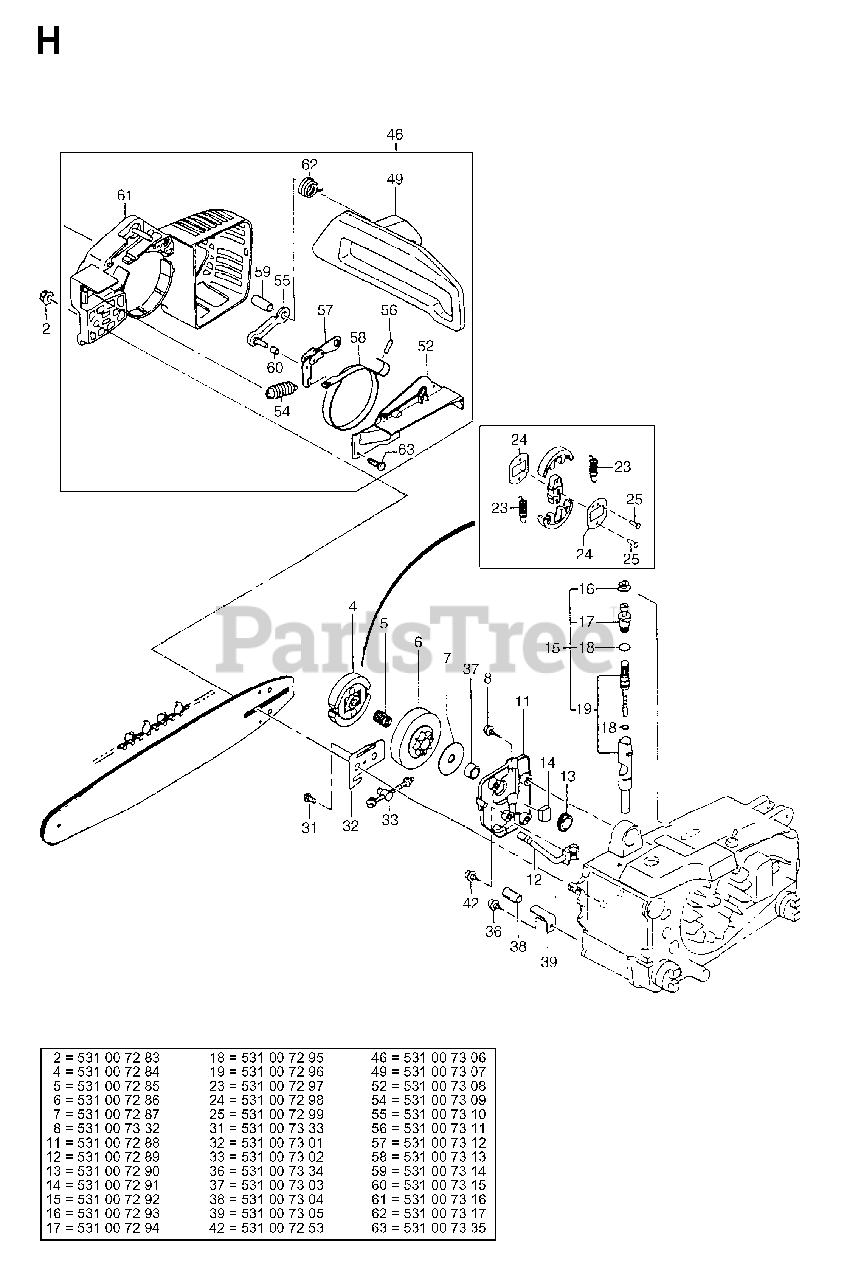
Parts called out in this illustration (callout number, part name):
5	NEEDLE BEARING
6	CLUTCH DRUM
14	PROTECTOR
19	PUMP PISTON
38	PROTECTOR
39	CHAIN CATCHER
46	CHAIN BRAKE
52	PROTECTOR
55	BRAKE LEVER
57	BRAKE LEVER
58	BRAKE BAND
